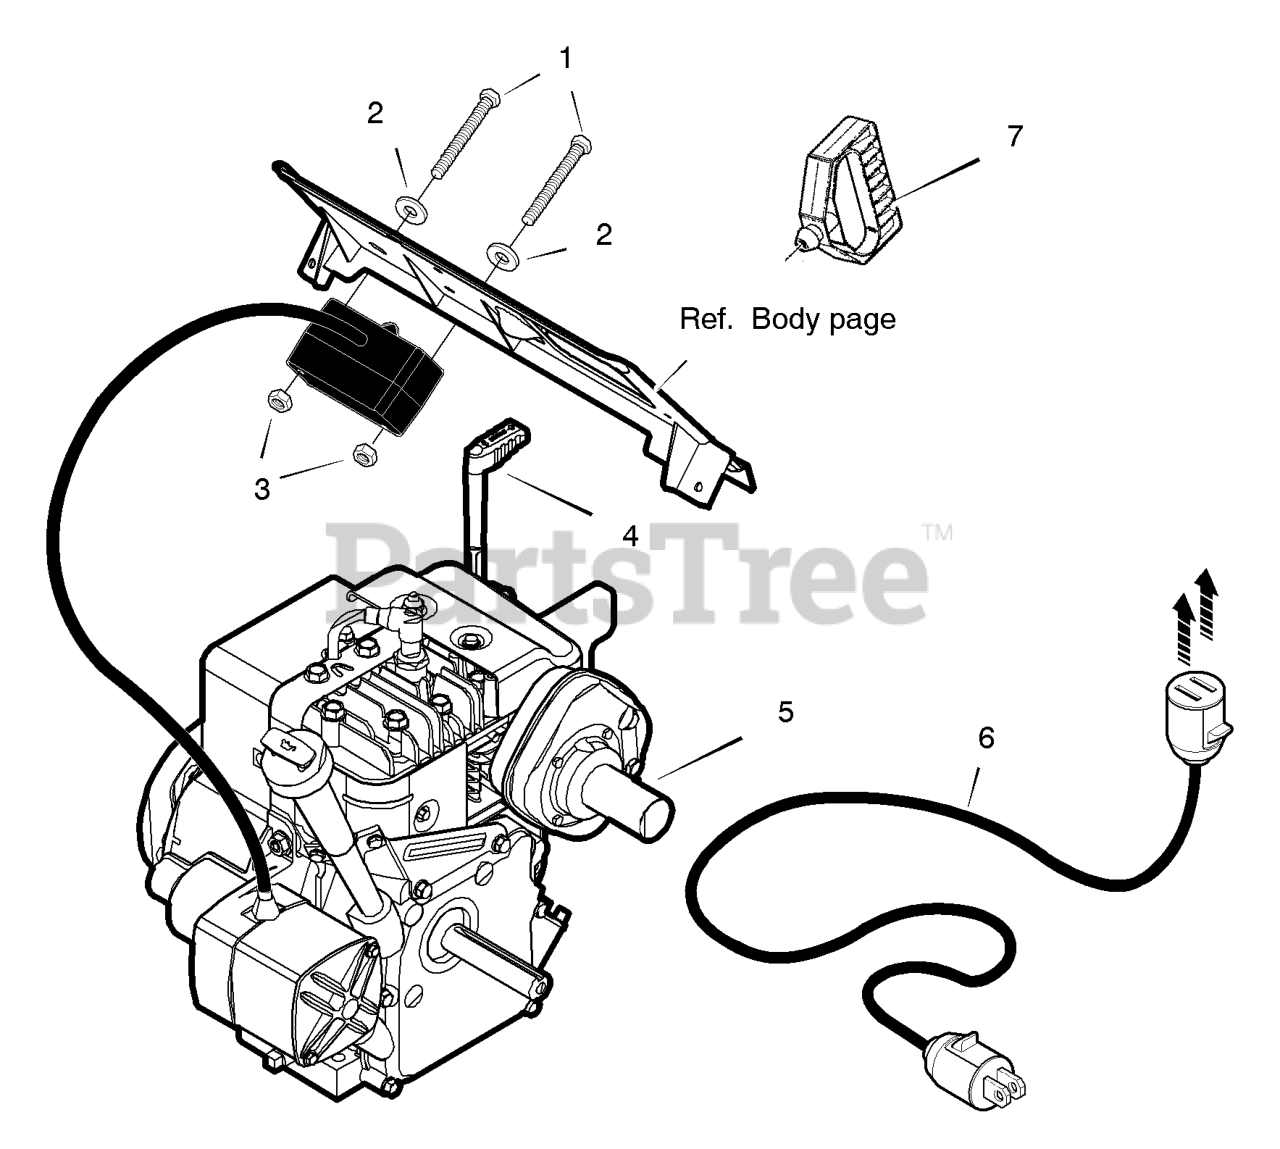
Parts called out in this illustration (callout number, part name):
1	Screw, No. 8-32 x 3.00 *
2	Washer *
3	Nut, Keps No. 8 *
4	Lever, Choke *
5-1	Muffler *
5-2	Gasket, Muffler *
5-3	Bolt, Muffler
5-4	Washer, Split Lock *
5-5	Nut, Hex 5/16-18 *
5-6	Bolt, Hex 5/16-18
6	CORD, Electric, 10FT. 110V
7	Grip, Mitten *
